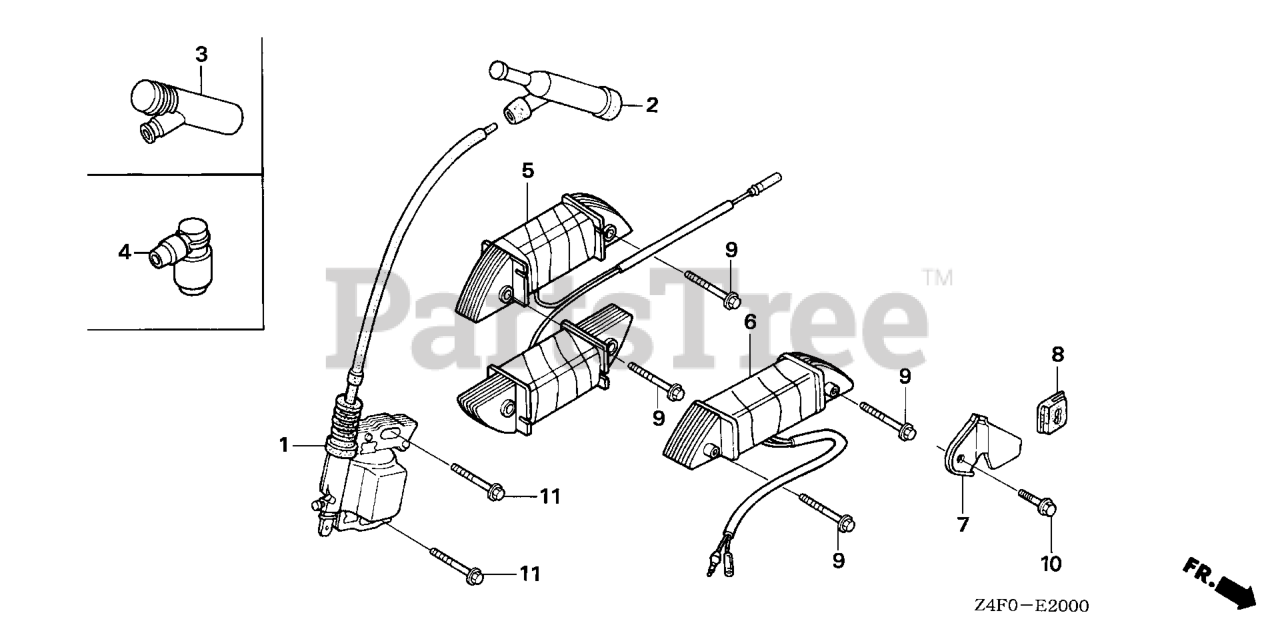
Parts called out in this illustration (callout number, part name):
1	COIL ASSY., IGNITION Use up to Engine SN 1530314.
2	CAP ASSY., NOISE SUPPRESSOR (Honda Code 3526837). (NICHIWA Y-EZ RTFM256)
11	BOLT, FLANGE (6X25) Use up to Engine SN 2056819.
